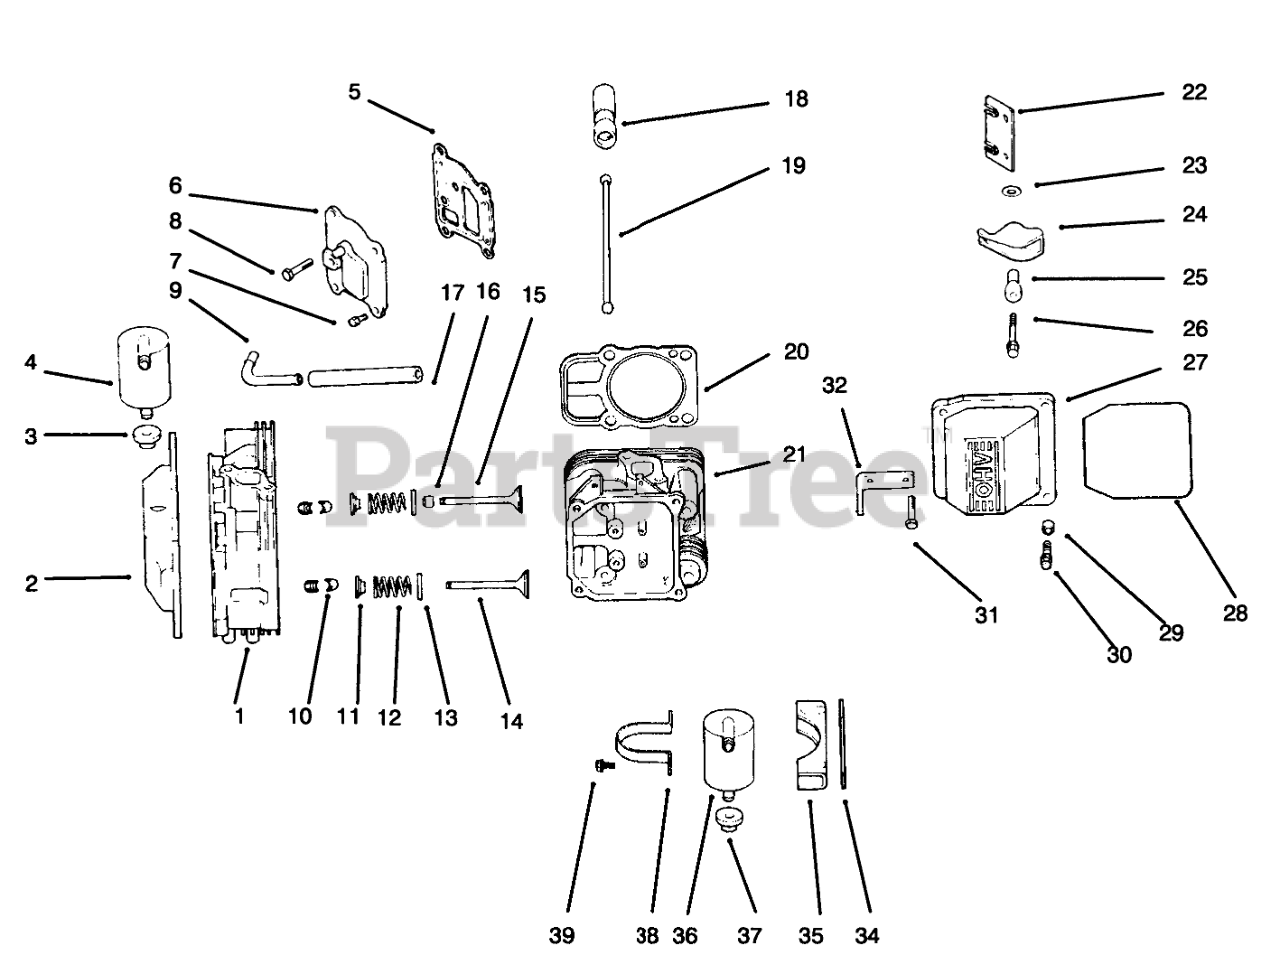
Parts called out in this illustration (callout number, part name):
1	#1 Cyl. Head Asm
2	Kit-Valve Cover/Breather (Incl. Ref.# 3 & 28-30)
3	Grommet-Rubber
4	Kit-Breather (Incl. Ref.# 3)
5	Gasket-Breather
6	Cover-Breather
7	Screw
8	Plug
9	Fitting
10	Retainer Kit
11	Cap-Spring, Valve
12	Spring-Valve
13	Retainer-Spring
14	Valve-Exhaust (Std)
15	Valve-Intake (Std)
16	Seal-Stem, Valve
17	Hose
18	Lifter-Valve
19	Rod-Push
20	Gasket-Cylinder Head
21	#2 Cyl. Head Asm,
22	Plate-Guide
24	Arm-Rocker
25	Pivot-Rocker Arm
27	Kit-Valve Cover (Incl. Ref. # 28-30)
28	"O"Ring
29	Spacer
30	Screw
31	Screw
32	Strap-Lifting
34	Spacer
35	Bracket
36	Separator-Oil Breather
37	Grommet
38	Strap-Lifting
